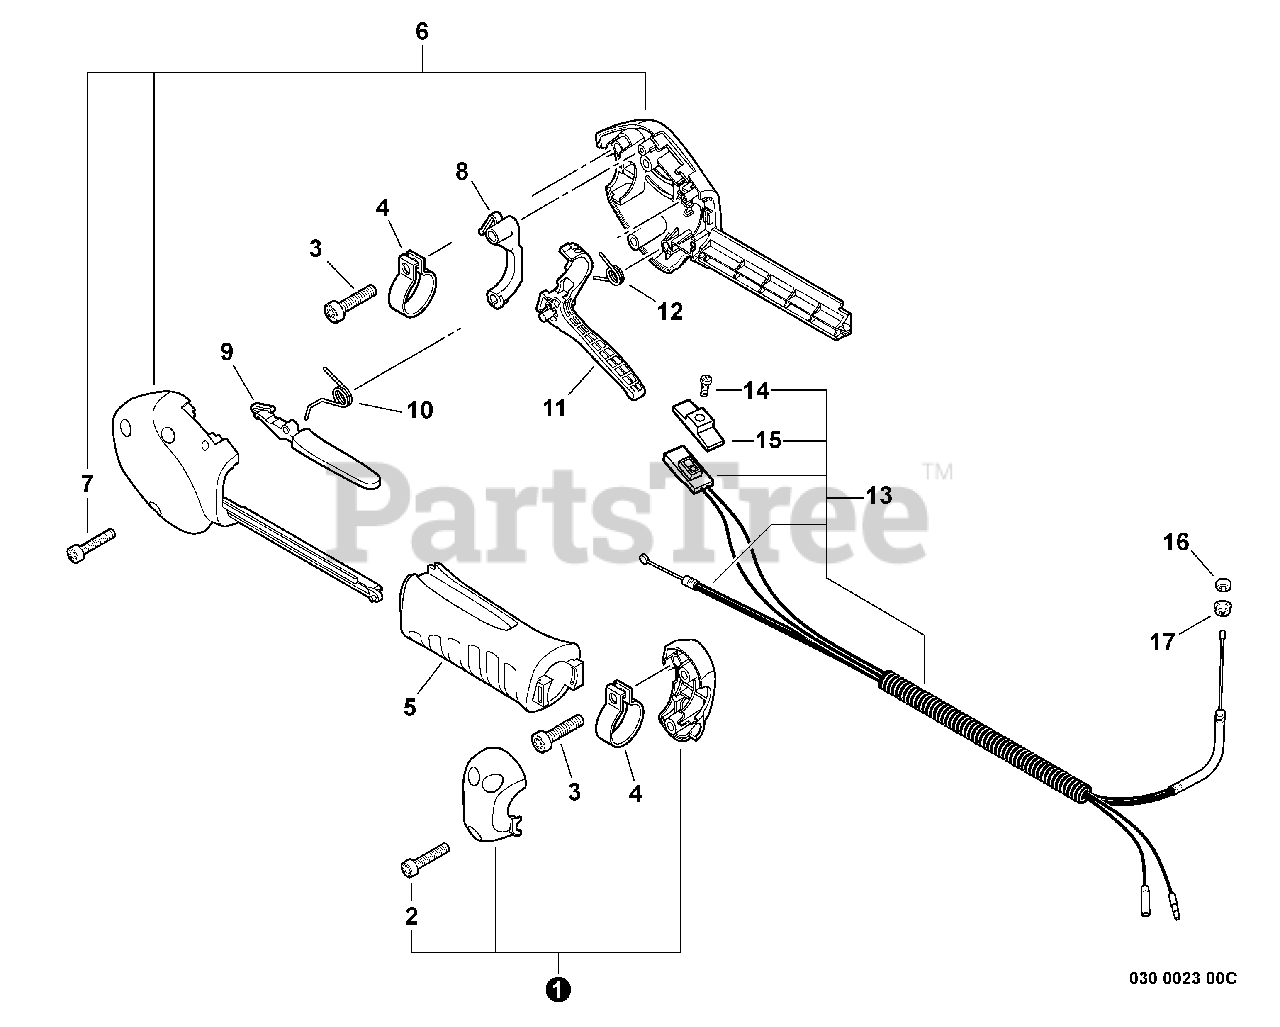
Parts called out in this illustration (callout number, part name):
1	HANDLE BRACKET KIT
2	SCREW - 4X20 -- TAPPING
3	SCREW - 5X20
5	GRIP, HANDLE
6	CONTROL HANDLE KIT
7	SCREW - 4X20 -- TAPPING
8	LOCKOUT, THROTTLE
9	LEVER, TRIGGER LOCKOUT
10	SPRING, LOCKOUT LEVER
11	TRIGGER, THROTTLE
12	SPRING, TRIGGER
13	CONTROL CABLE ASSY
14	SCREW - 3X10
15	KNOB, SWITCH - ORANGE
17	NUT - 6 -- FLANGE
